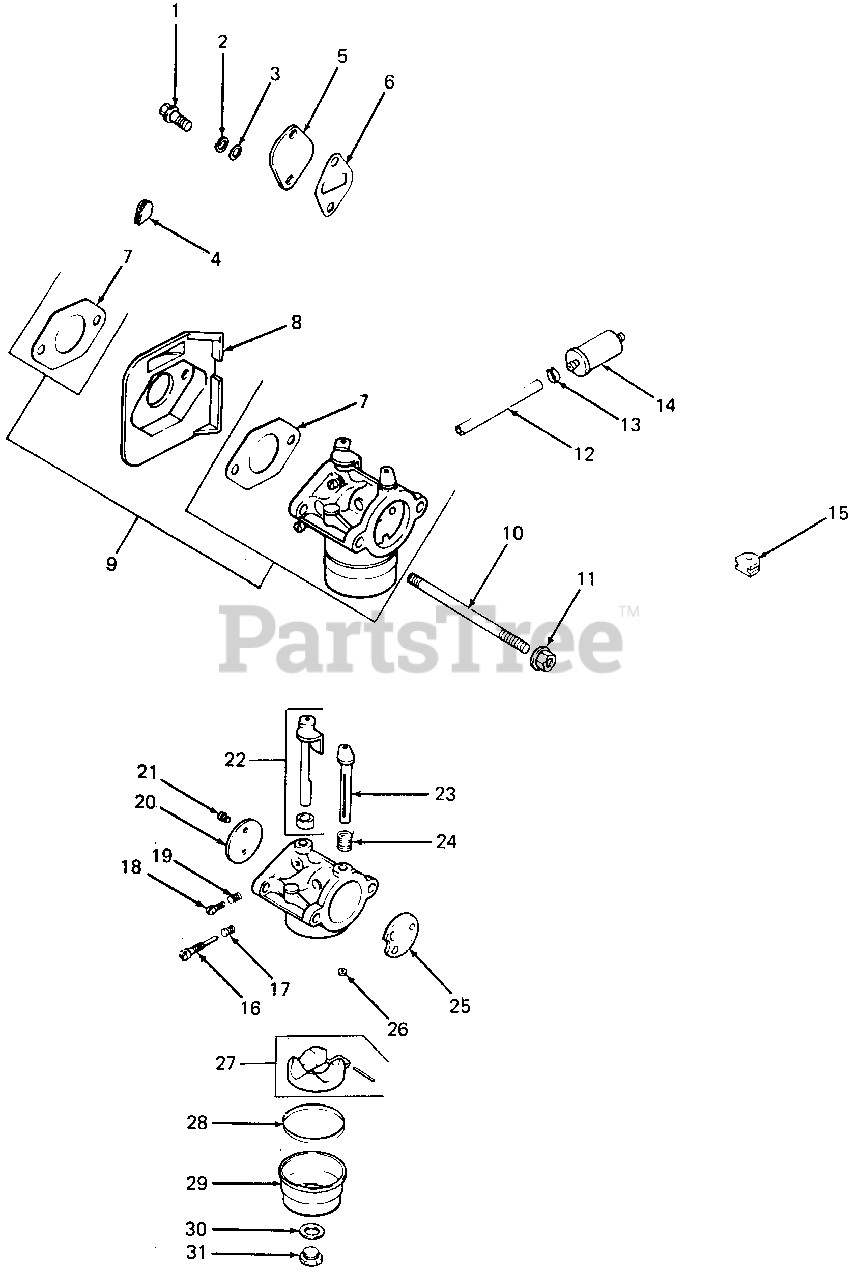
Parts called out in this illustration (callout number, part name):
1	Screw, Fuel Pump, M6 X 1.0 X 20
2	Washer, Lock, 1/4
3	Washer, Plain, 1/4
4	Grommet, Blower Housing
5	Cover, Fuel Pump
6	Gasket, Fuel Pump
7	Gasket, Carburetor
8	Deflector, Heat
9	Carburetor Assy w/Gasket
10	Stud, Carburetor, M6 X 1.0 X 110
11	Nut, Carburetor, M6 X 1.0
12	Hose, Fuel, 3"
13	Clamp, Fuel Line
14	Filter, Fuel
16	Needle, Idle Fuel Adj
17	Spring, Idle Fuel
18	Screw, Idle Speed Adj
19	Spring, Idle Speed
20	Plate, Throttle
21	Screw, Throttle Plate
22	Shaft, Throttle w/Lever & Seal
23	Shaft, Choke
24	Spring, Choke Return
25	Plate, Choke
28	Gasket, Bowl
30	Gasket, Bowl Retainer Screw
31	Screw, Bowl Retainer
